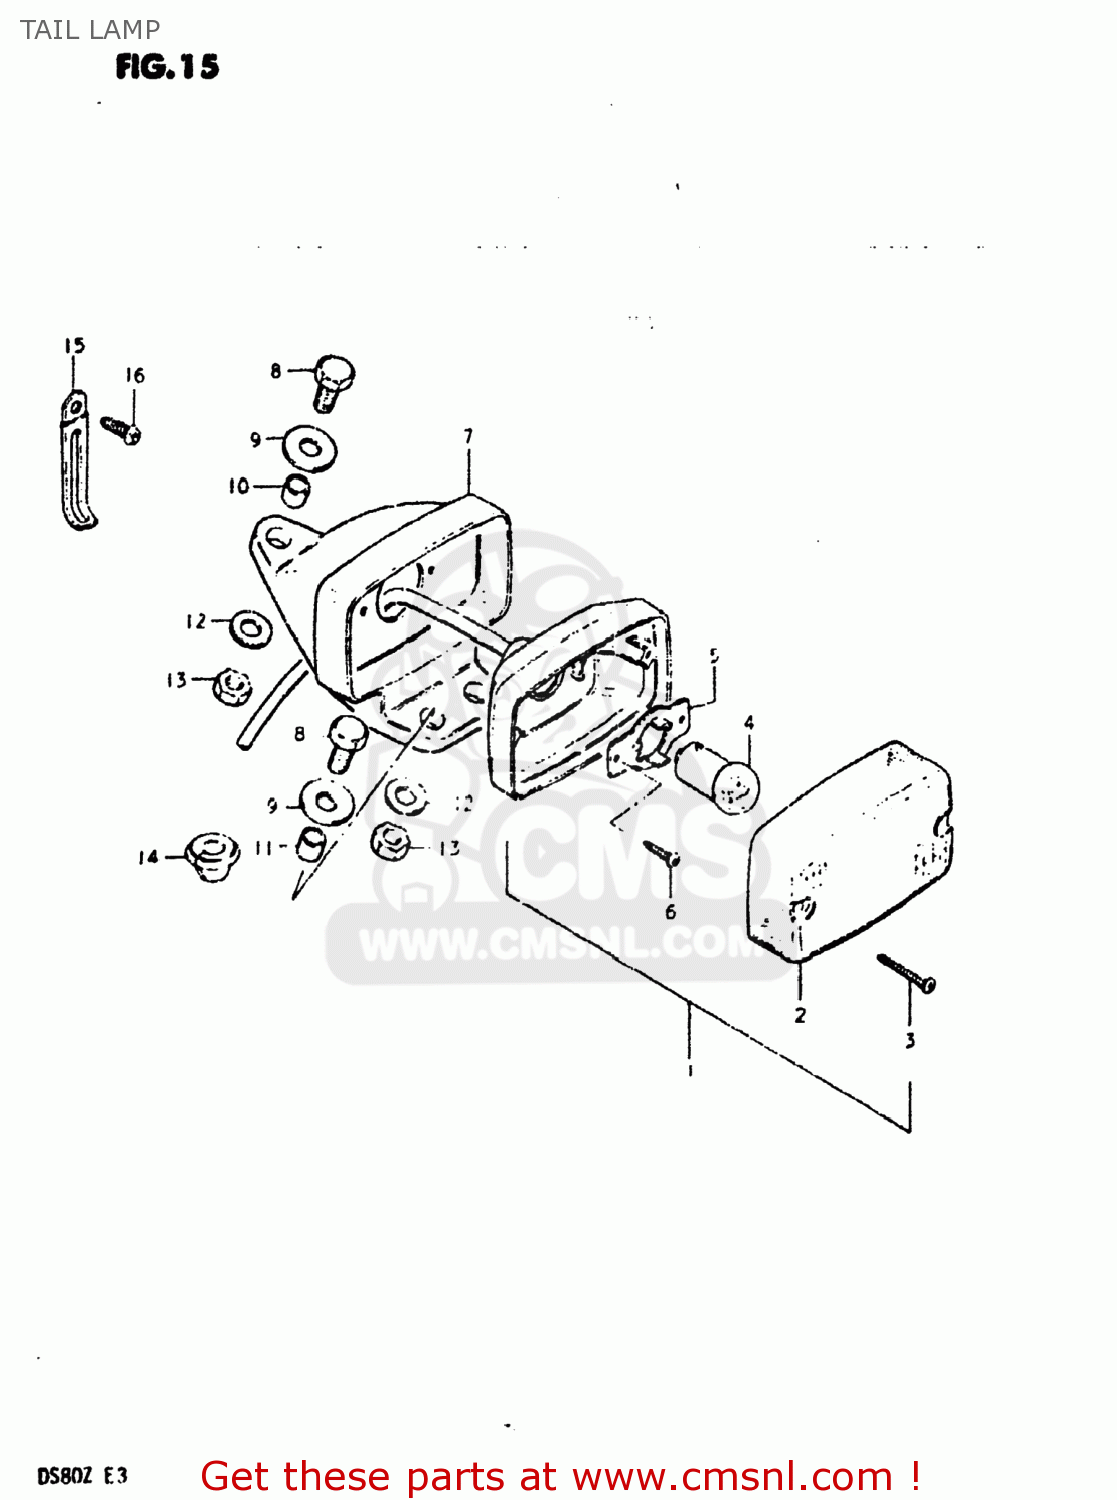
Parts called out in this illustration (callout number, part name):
1	LAMP UNIT,TAIL
2	LENS
3	SCREW
4	BULB(6V5W,TOKAI DENSO)
5	PLATE,TURN SIGNAL
6	SCREW
7	BRACKET
8	BOLT, UPPER
9	WASHER (6.5X20X1.2)
10	SPACER(6.1X9X7.5)
11	SPACER (6.1X9X9)
12	WASHER
13	NUT
14	GROMMET
15	CLAMP L:35
16	CROSS SCREW (4X8)
